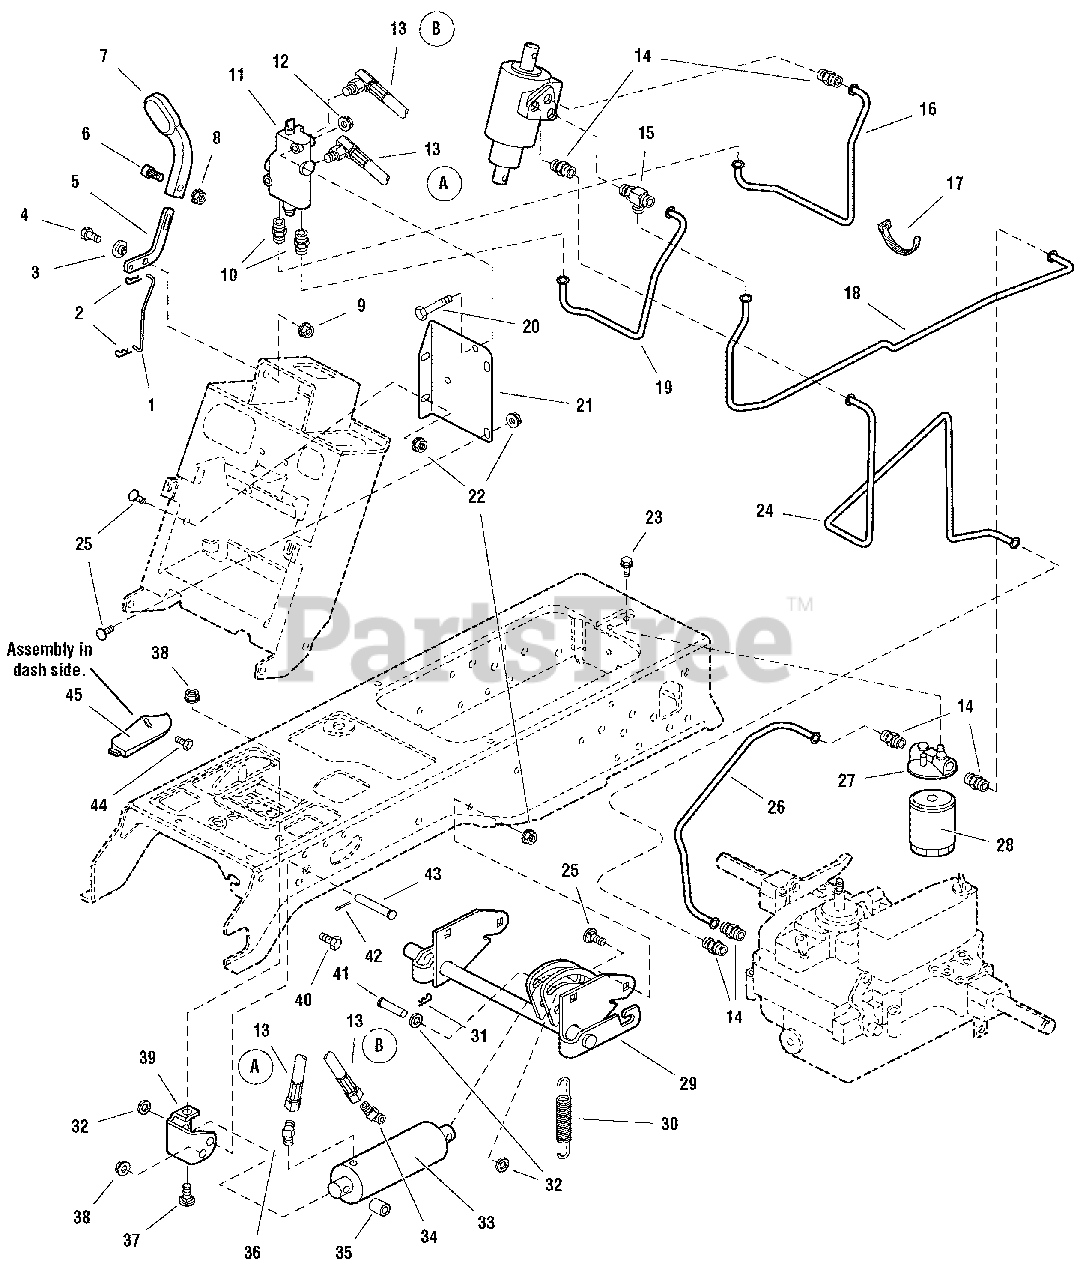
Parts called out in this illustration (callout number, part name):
1	ROD, Hydraulic Link
2	PIN, Cotter
3	SPACER, Hydraulic Lift Pivot
4	CAPSCREW, Hex Head, 5/16-18 x 1, Black
5	LEVER
6	SCREW, Torx Plus Socket Head, 1/4-20 x 7/8
7	HANDLE
8	NUT, Hex Lock, ESNA Light, 1/4-20
9	NUT, Hex Lock ESNA Light, 5/16-18
10	FITTING, Straight, 11/16-16, 3/4-16
11	VALVE, Hydraulic
12	NUT, Hex KEPS, 1/4-20
13	HOSE ASSEMBLY, Hydraulic, Rubber, 12" long
14	FITTING, Straight, 9/16-18, 11/16-16
15	FITTING, Hose Tee, 11/16-16, .562-18
16	TUBE, Hudraulic, Steel, 5 Bends
17	TIE, Self Locking
18	TUBE, Hudraulic, Steel, 8 Bends
19	TUBE, Hudraulic, Steel, 5 Bends
20	CAPSCREW, Hex Head, 1/4-20 x 2
21	SUPPORT, Control Valve
22	NUT, Hex KEPS, 5/16-18
23	CAPSCREW, Hex Flange Whiz Lock, 1/4-20
24	TUBE, Hudraulic, Steel, 5 Bends
25	CARRIAGE BOLT, 5/16-18 x 3/4
26	TUBE, Hudraulic, Steel, 5 Bends
27	BASE, Oil Filter
28	FILTER, Oil
29	SHAFT ASSEMBLY
30	SPRING
31	CLIP, Hair Pin
32	WASHER, 1/2 x 7/8
33	CYLINDER, Hydraulic
34	FITTING, Elbow, 90 Degree, 9/16-18, 1/4
35	SPACER, 17/32 x 3/4 x 1-1/32
36	FITTING, Elbow, 45 Degree, 9/16-18, 1/4
37	CARRIAGE BOLT, 3/8-16 x 1
38	NUT, Hex KEPS, 3/8-16
39	SUPPORT, Cylinder to Frame
40	CAPSCREW, Head Head, 3/8-16 x 1
41	PIN, Flat Head Drilled
42	PIN, Cotter
43	PIN, Clevis
44	SCREW, Pan Head, # 8-16 x 1/2
45	COVER, Dash Black (SEE NARATIVE)
